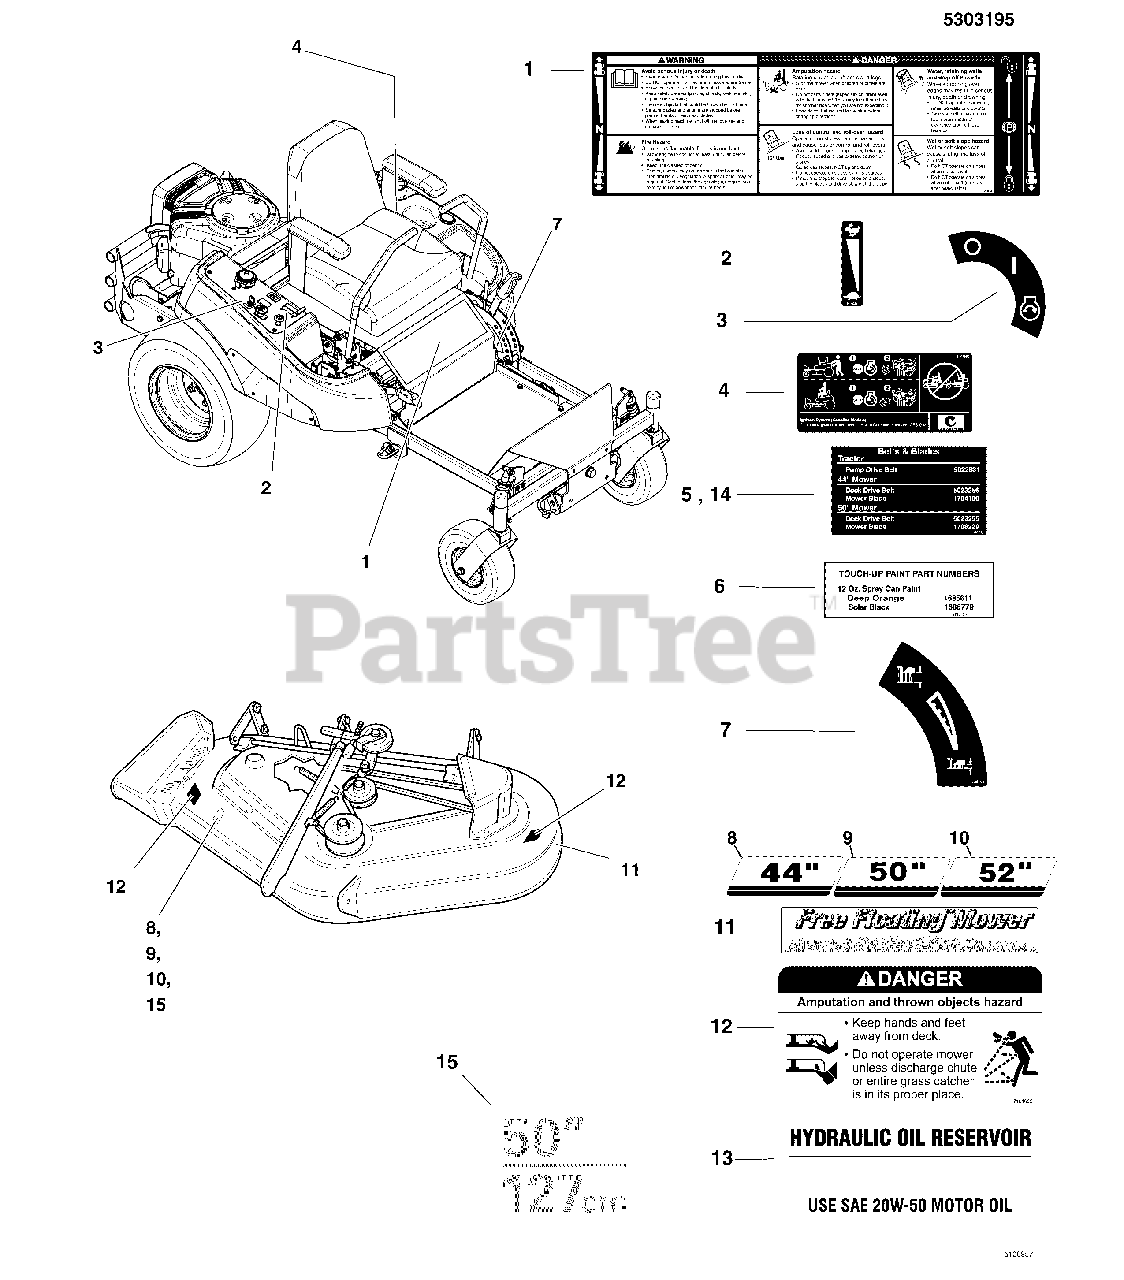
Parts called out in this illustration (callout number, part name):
1	DECAL, MAIN SAFETY
2	DECAL, THROTTLE CONTROL
3	DECAL, IGNITION SWITCH
4	DECAL, CZT HYRDO RELEASE
5	DECAL- BELT & BLADE
6	DECAL-TOUCH UP PAINT ORANGE,BLACK,RED
7	DECAL, HEIGHT OF CUT
8	DECAL-44"- SILVER ON BLACK W/STRIPE
9	DECAL-50"- SILVER ON BLACK W/STRIPE
10	DECAL-52"- SILVER ON BLACK W/STRIPE
11	DECAL-FREE FLOATING MOWER- SILVER
12	DECAL, DANGER DO NOT OPERATE W/O DEFLECT
13	DECAL, HYDRAULIC OIL, SAE 20W50
14	DECAL, BELT & BLADE, CHAMP, 52
15	DECAL, MOWER WIDTH 50IN/127CM
